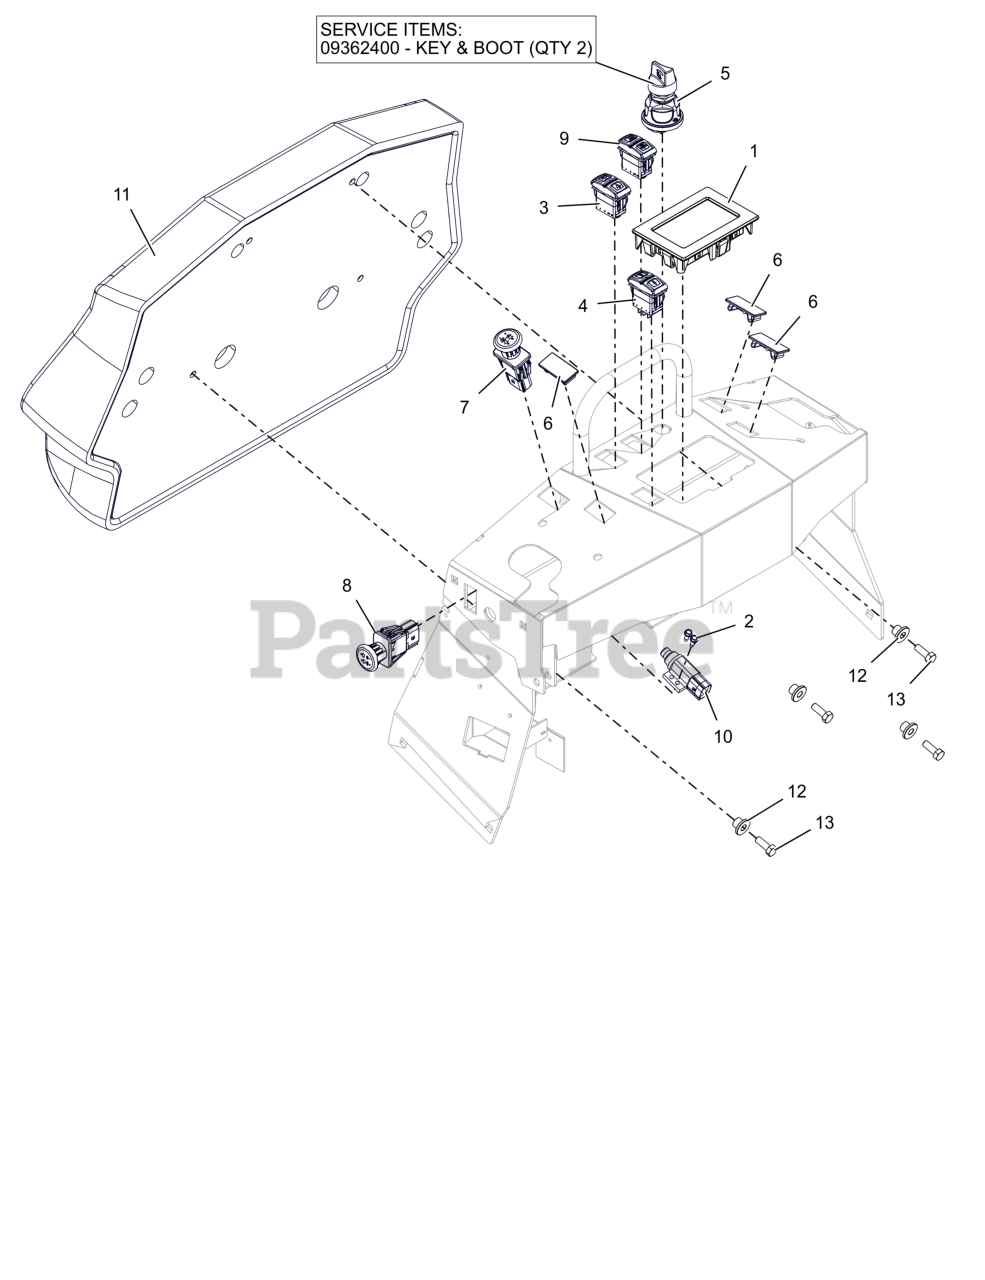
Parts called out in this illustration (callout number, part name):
1	DISPLAY, PSEV
2	SCR,TAP #10-24X.50 HWH TR ZCC
3	SWITCH, TOGGLE - SPEED
4	SWITCH, ROCKER - DISPLAY
5	SWITCH, KEY (SEALED)
5	KEY & BOOT (QTY 2)
6	PLUG, SWITCH
7	SWITCH, PTO - RED
8	SWITCH, PARKING BRAKE
9	SWITCH, TOGGLE ECO
10	SWITCH, SEALED PLUNGER
11	PAD- PSEV OPERATOR
12	BSHG-FLG .325X.500X.513X.875
13	BLT, HEX .31-18X.875 G5 ZCC
